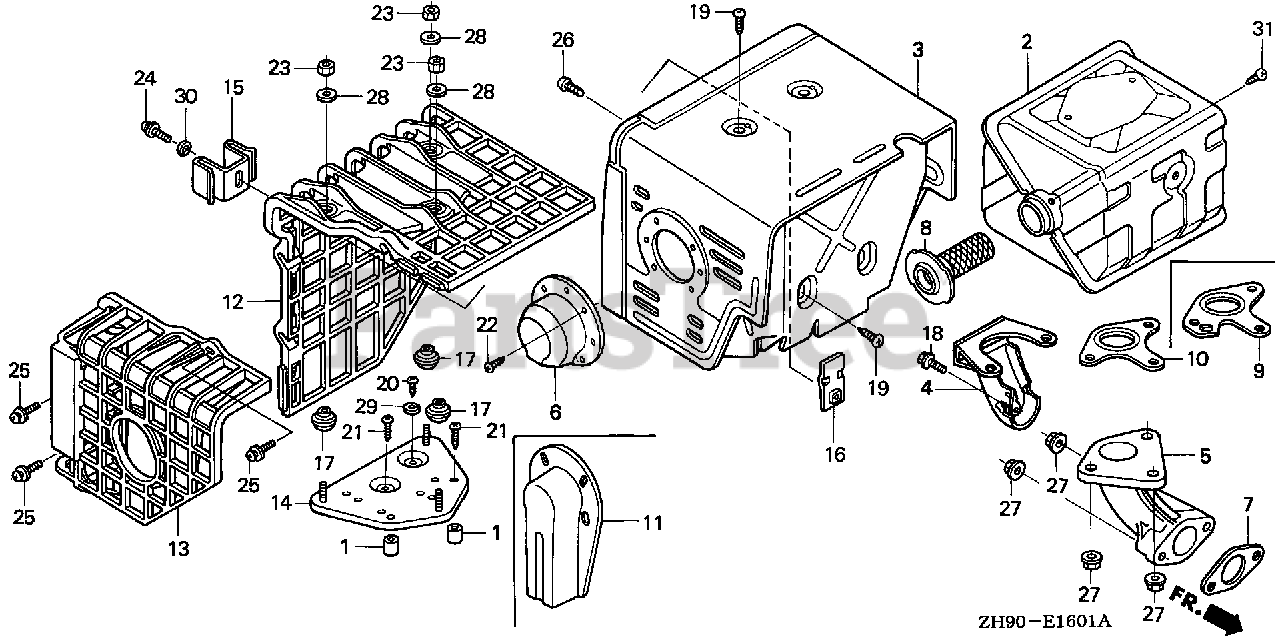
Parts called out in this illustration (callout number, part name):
2	MUFFLER (100DB)
3	PROTECTOR, MUFFLER
7	GASKET, EX. PIPE
8	ARRESTER, SPARK
9	GASKET, MUFFLER (ARRESTER) (NIPPON LEAKLESS)
10	GASKET, MUFFLER (NIPPON LEAKLESS)
19	SCREW, TAPPING (5X8)
26	SCREW, TAPPING (6X10)
27	NUT, FLANGE (8MM)
31	SCREW, TAPPING (5X8)
31	SCREW, TAPPING (4X6)
